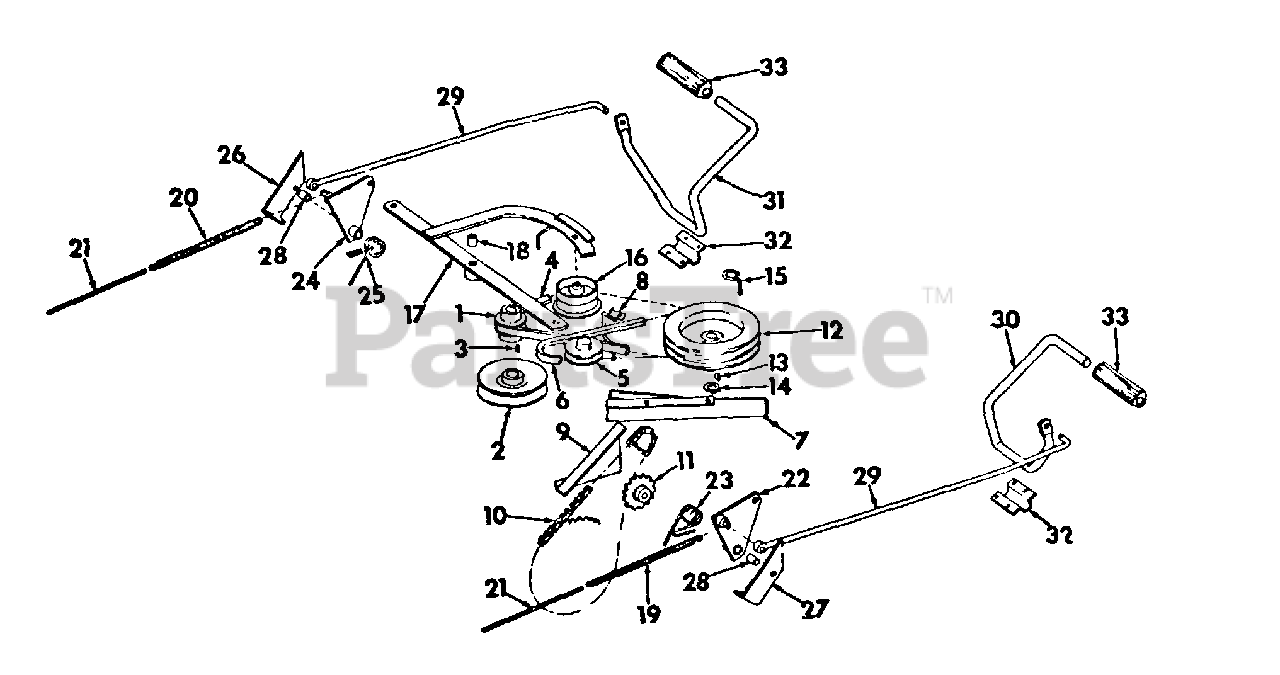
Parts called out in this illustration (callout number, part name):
1	PULLEY, FORWARD DRIVE
2	PULLEY ASSY, MOWER DRIVE
3	KEY, 5/32 X 5/8 SAE 6 WOODRUFF
4	BELT, FORWARD DRIVE
5	PULLEY, REVERSE DRIVE
6	BELT, REVERSE DRIVE
7	GUIDE ASSY, BELT
8	GUIDE ASSY, BELT
9	SHIELD, DRIVE CHAIN
10	CHAIN, FINAL REDUCTION
11	SPROCKET, CHAIN IDLER - 15 T
12	PULLEY, TRANSMISSION DRIVE
13	KEY, 3/16 X 3/4 WOODRUFF 9
14	RING, RETAINING
15	GUIDE ASSY, BELT
16	PULLEY, FORWARD REVERSE IDLER
17	ARM ASSY, SHIFTER PIVOT
18	BUSHING, SHIFTER ARM
19	SPRING, DRIVE TENSION FORWARD
20	SPRING, DRIVE TENSION REVERSE
22	LEVER ASSY, CONTROL RH
23	SPRING, RETURN RH
24	LEVER ASSY, CONTROL LH
25	SPRING, RETURN LH
26	PLATE, STOP LH
27	PLATE, STOP RH
28	BUSHING, CONTROL LEVER
29	ROD, CONTROL
30	ROD, TRANSMISSION CONTROL PEDAL RH
30	ROD TRANSMISSION CONTROL PEDAL RH
31	ROD, TRANSMISSION CONTROL PEDAL LH
31	ROD TRANSMISSION CONTROL PEDAL LH
32	CLAMP, PEDAL PIVOT
